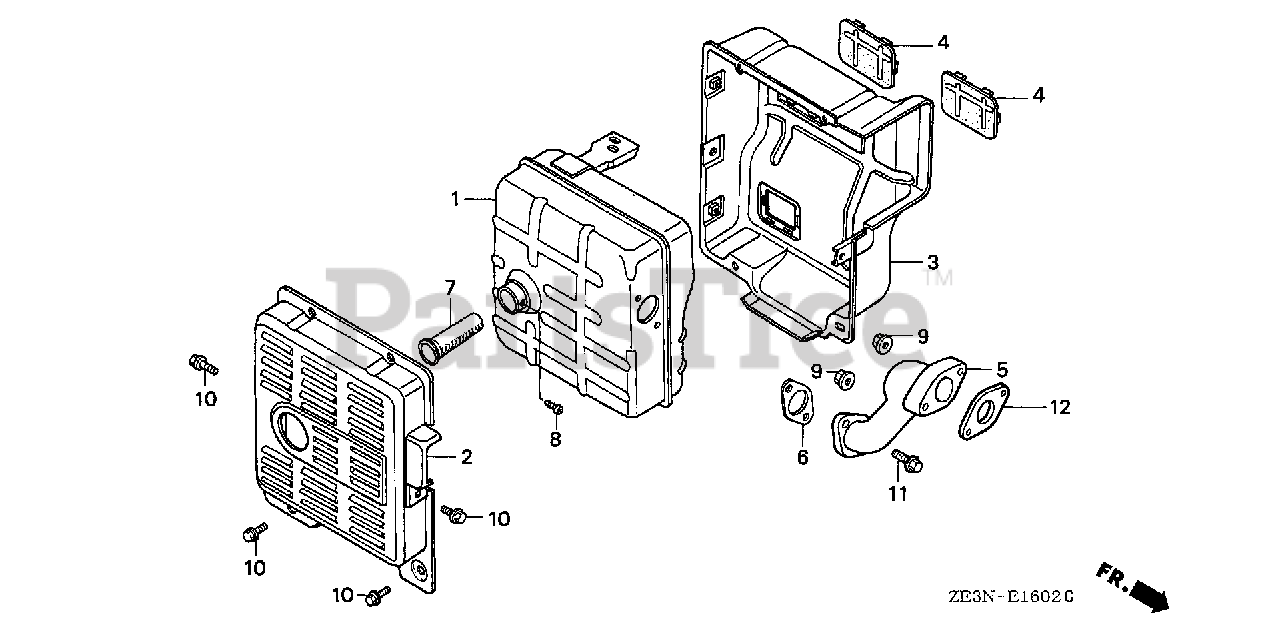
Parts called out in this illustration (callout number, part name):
1	MUFFLER
2	PROTECTOR, MUFFLER (OUTER)
3	PROTECTOR, MUFFLER (INNER)
4	SEAL, MUFFLER PROTECTOR
5	PIPE, EX.
6	GASKET, EX. PIPE
7	ARRESTER, SPARK
8	SCREW, TAPPING (4X8)
9	NUT, FLANGE (8MM)
10	BOLT, FLANGE (6X12)
11	BOLT, FLANGE (8X20)
12	GASKET, EX. PIPE
12	GASKET, EX. PIPE (WACKER)
